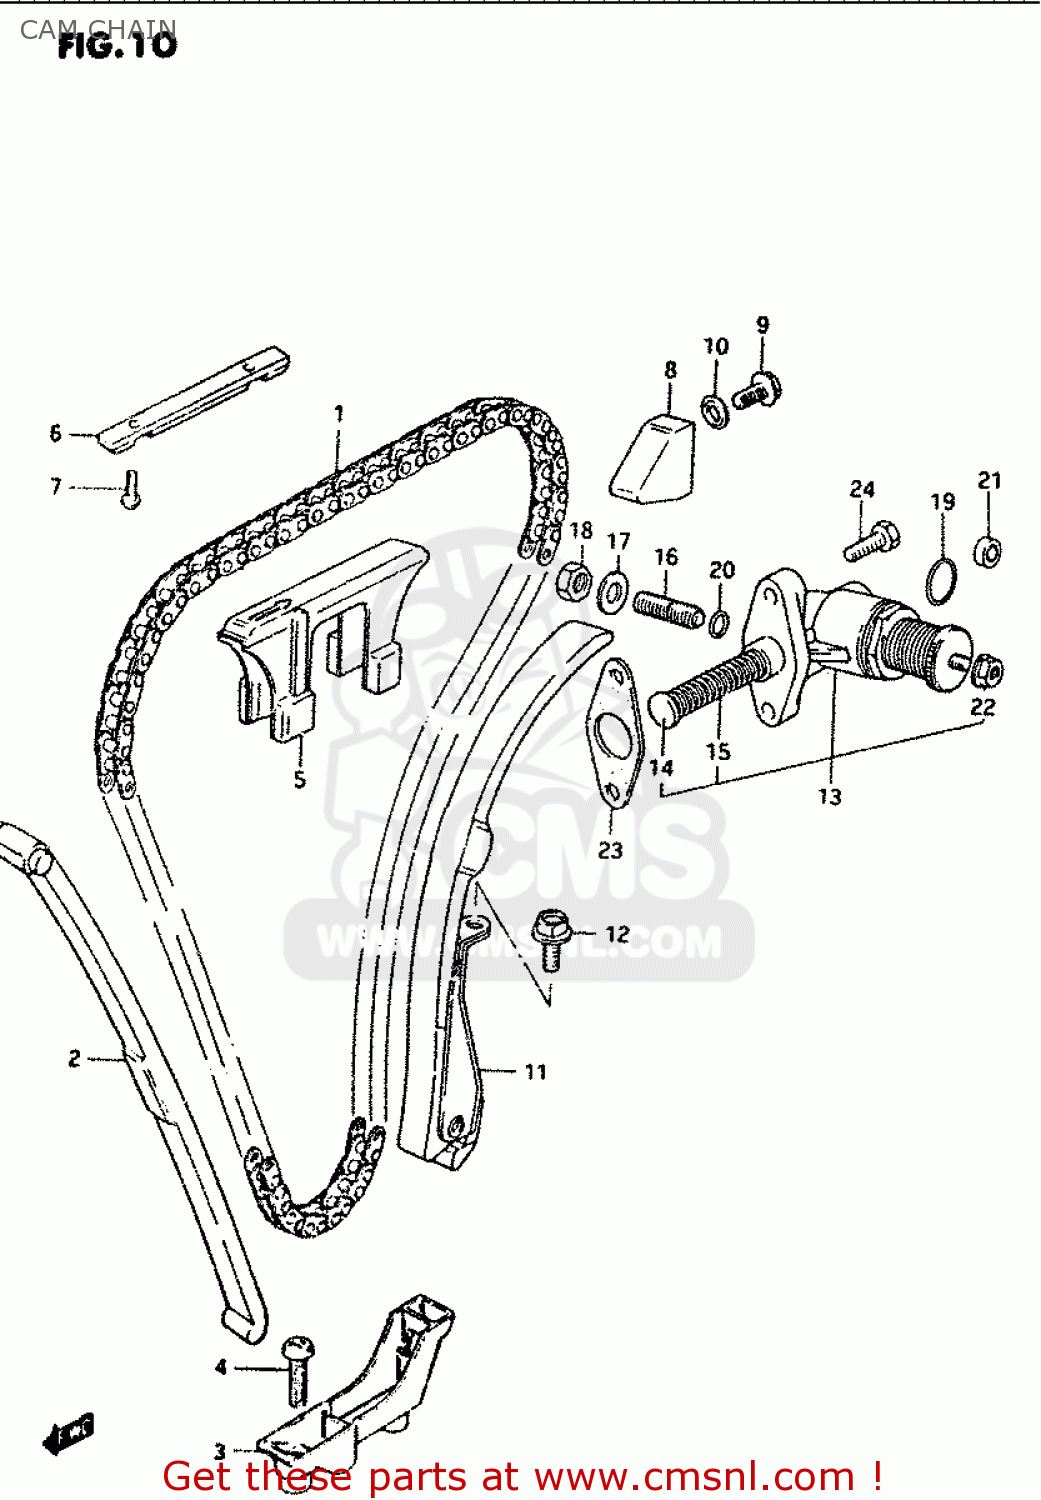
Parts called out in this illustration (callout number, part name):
1	CHAIN,CAMSHAFT DRIVE
2	GUIDE,CAM CHAIN NO.1
3	HOLDER,CAM CHAIN GUIDE
4	SCREW
5	GUIDE,CAM CHAIN NO.2
6	GUIDE,CAM CHAIN
7	SCREW
8	GUIDE,CAM CHAIN
9	BOLT 6X12
10	WASHER
11	TENSIONER,CAM CHAIN
12	BOLT
13	ADJUSTER ASSEMBLY,TENSIONER
14	ROD,PUSH
15	SPRING
16	SCREW,TENSIONER ADJUST
17	WASHER,8.5X16X
18	NUT
19	O RING(D:2.4,ID:20.8)
20	O RING(D:1.9,ID:5.7)
21	SEAL,OIL(10X16X4)
22	NUT 6MM
23	GASKET,TENSIONER ADJUSTER (MCA)
24	SCREW
